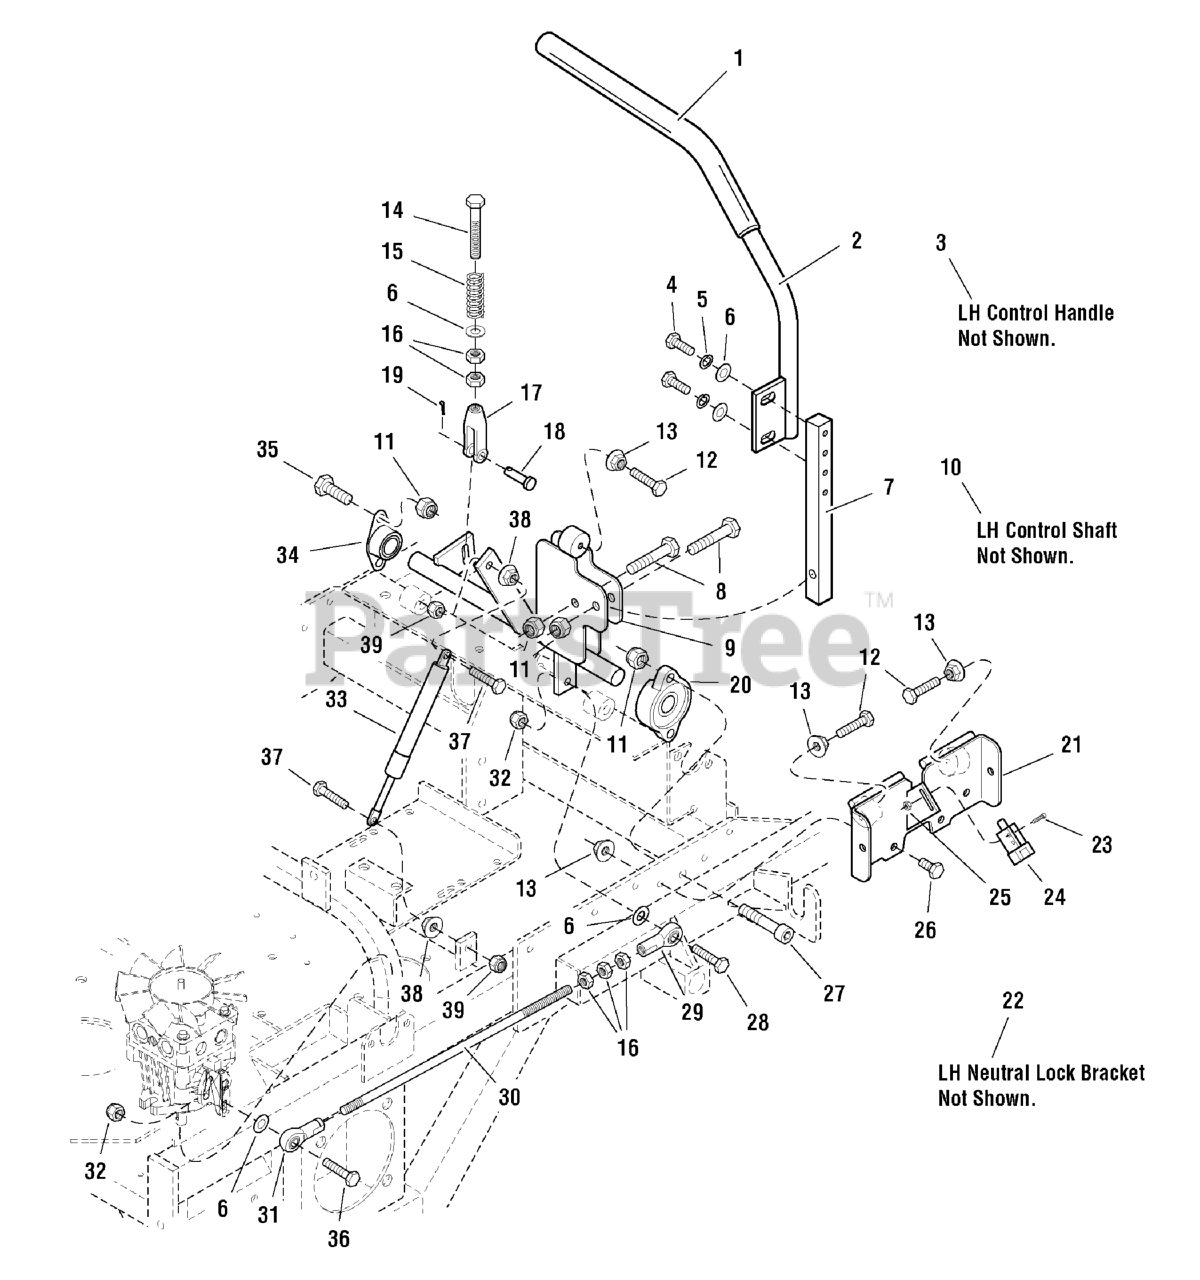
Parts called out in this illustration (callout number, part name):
1	GRIP, Foam
2	KIT, HANDLE BAR REPLACE, L/R
4	BOLT, 5/16-18 X 1 GD5 YZ
5	WASHER, 5/16 LOCK CZ
6	WASHER, 5/16" SAE
7	MOUNT, CONTROL ARM - BLK
8	BOLT, 3/8-16 X 1-3/4" GD5 CZ
9	CONTROL SHAFT-RH
11	NUT, 3/8-16 HEX NYLON LOCK
12	BOLT, 5/16-18 x 1-3/4 TFL
13	NUT, 5/16-18 HEX SERRATED FLANGE (SMALL)
14	REVERSE RETURN BOLT
15	SPRING, Compression
16	NUT, 5/16-24 Hex
17	CLEVIS, 5/16-24, Plastic
18	CLEVIS PIN, 5/16 x 1
19	PIN, 3/32 X 0.750, COT, ZINC/CLEAR
20	BEARING, Flange
21	NEUTRAL LOCK BRACKET-RH
23	SCREW, #10-24 x 1/2
24	SWITCH, Plunger, NO
25	NUT, #10-24 Hex
26	BOLT, 5/16-18 X 1 GD5 YZ
27	BOLT, Allen Head, 3/8-16 x 1-1/4
28	BOLT, 5/16-18 x 1-1/4
29	BALL JOINT 5/16-24 RH FEMALE BRONZE RACE
30	HYDRO CONTROL ROD
31	BALL JOINT 5/16-24 LH FEMALE BRONZE RACE
32	NUT, 5/16-18 Hex Nylon Lock
33	DAMPENER
34	BEARING, Flange
35	BOLT, 3/8-16 X 1" GD5 CZ
36	BOLT, 5/16-18 x 1-1/8
37	BOLT, M8 x 35MM
38	NUT, M8-1.25 Hex Serrated Flange
39	NUT, M8-1.25 Hex Nylon Lock
